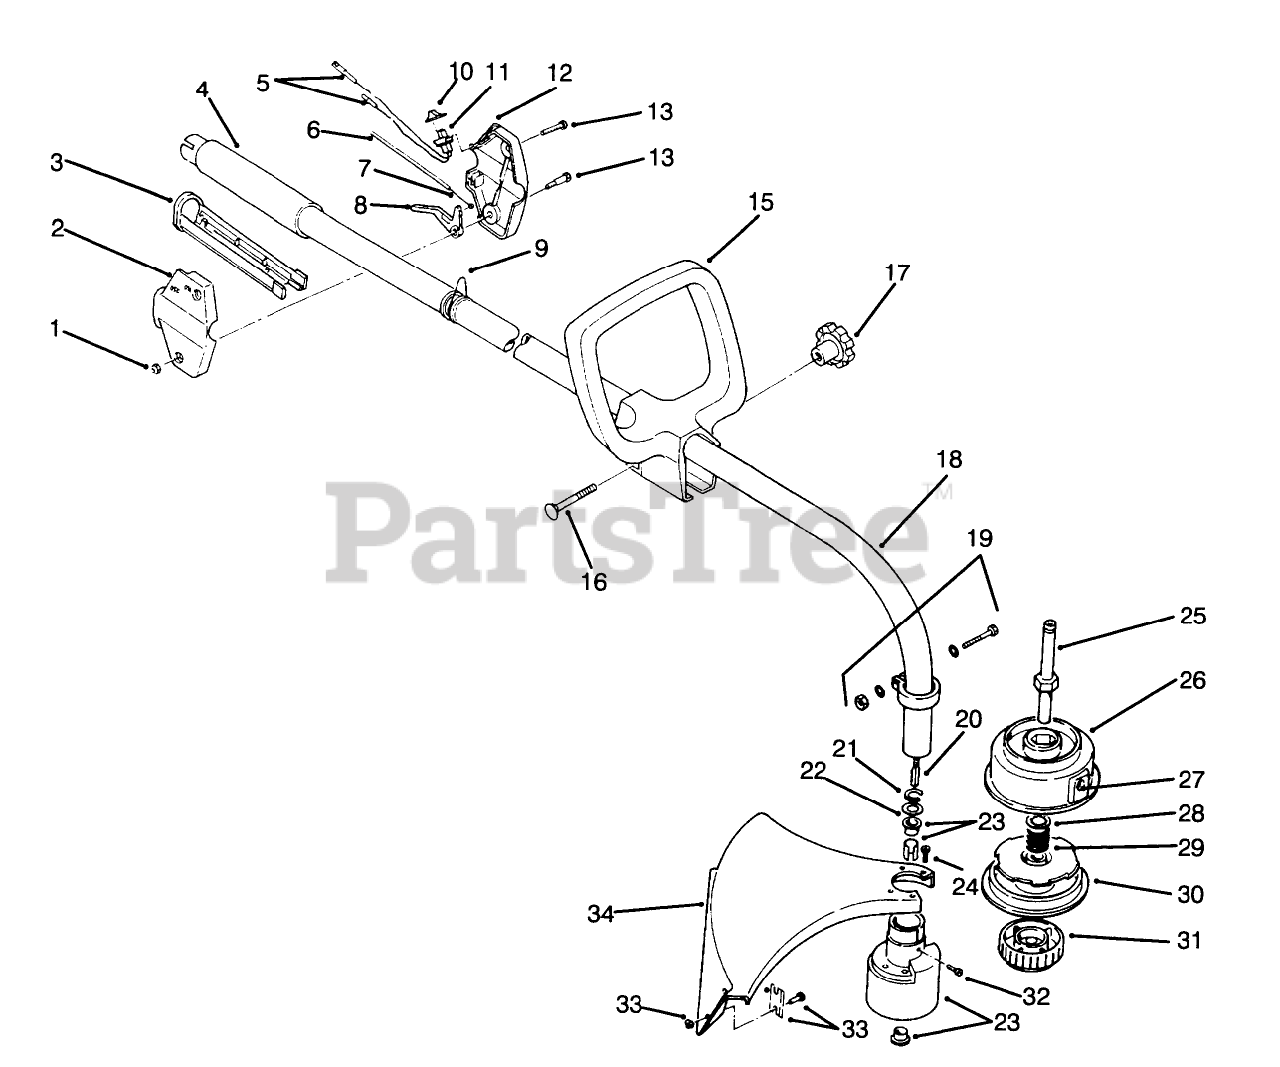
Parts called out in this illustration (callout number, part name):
1	NUT-LOCK, NI
3	TROUGH 1"
4	GRIP - RUBBER
7	THROTTLE CABLE
10	SWITCH COVER
11	SWITCH
12	HOUSING LH
19	CLAMP ASM - UPPER
21	RETAINING RING
22	WASHER
23	BUSHING HSG ASM
24	GUARD MTG SCREW ASM
26	OUTER SPOOL EYELET ASM
27	EYELET
28	RETAINER WASHER
29	SPRING
30	REEL - INNER
31	KNOB ASSEMBLY-SMALL BUMP
32	ANTI-ROTATION SCREW
33	BLADE ASM
